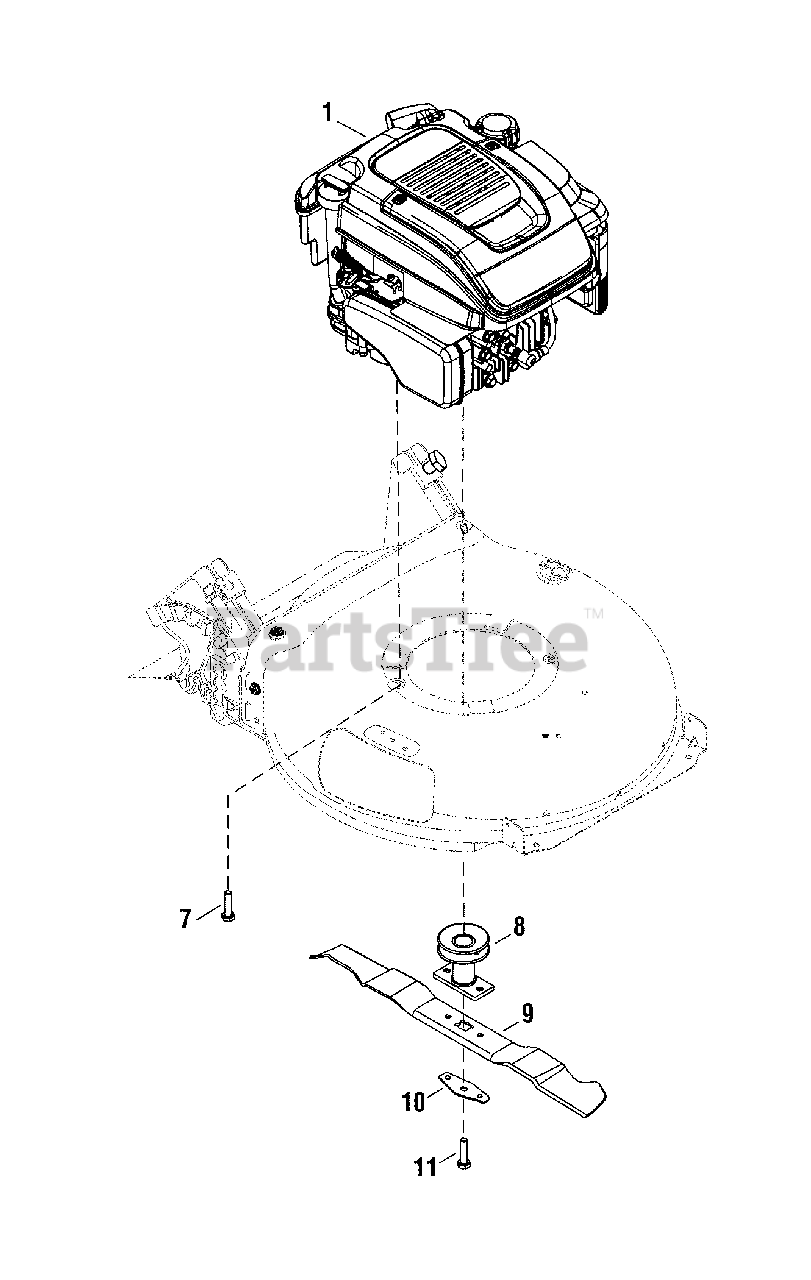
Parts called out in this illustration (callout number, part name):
1	* ENGINE, Briggs & Stratton, Mod. 103M02-0002-F1
7	SCREW, Engine Mounting, 3/8-16 x 1
8	* Engine, 14.5 Briggs Euro (w/oil filter)
9	BLADE, Mulching
10	SUPPORT, Blade Bell
11	SCREW Hex, 3/8-24 x 1-1/2
